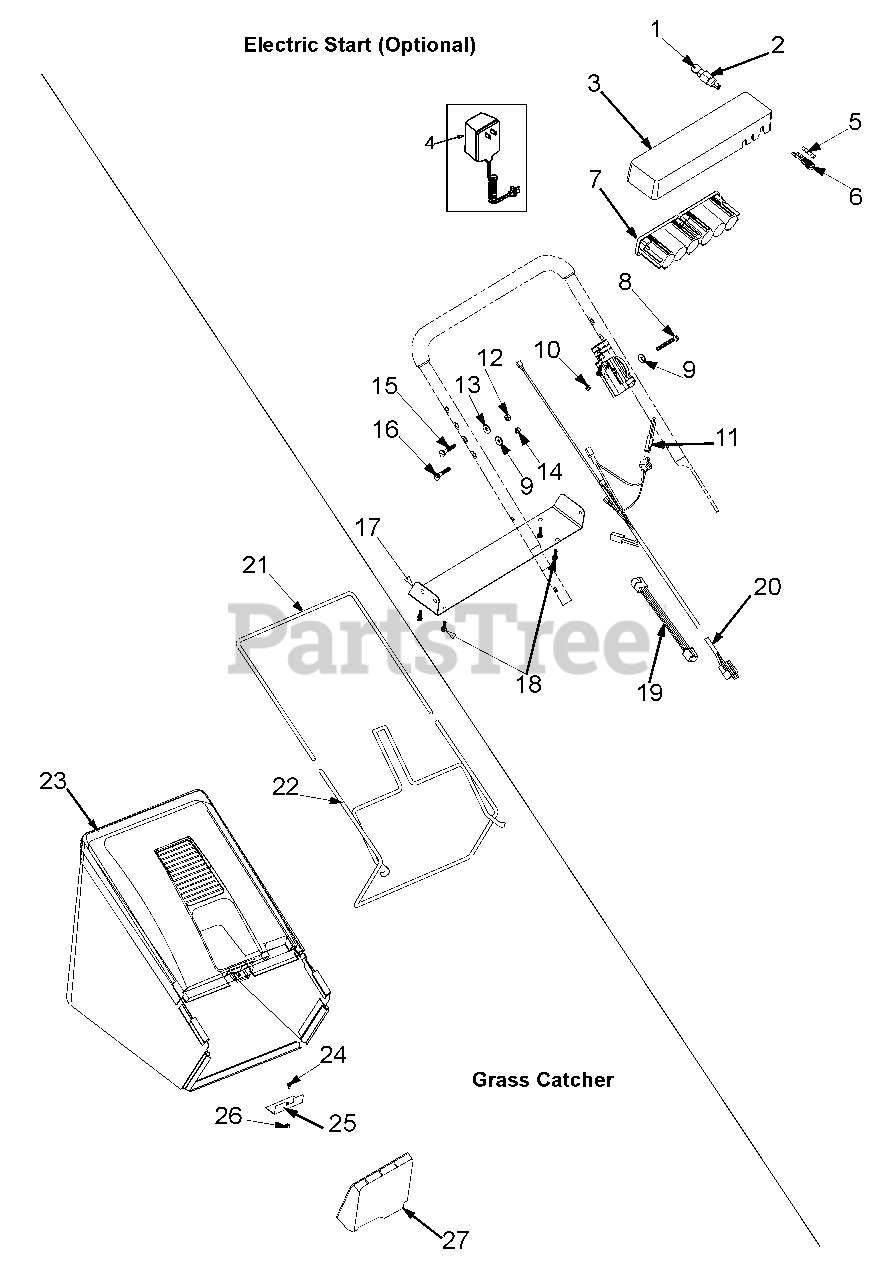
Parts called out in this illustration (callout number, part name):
1	Ignition Key
2	Key Switch
3	Battery Tray
4	Battery Charger
5	Fuse 7.5 Amp
6	Fuse Holder
7	Battery 12V
8	Hex Screw: 1/4-20: 2.0
9	Bell Washer .265 x .75 x .062
10	Special Hex Nut 5/16-18
11	Plug
12	Nut 5/16-18
13	Bell Wash .340 ID x .872 OD
14	Hex Nut 1/4-20
15	Carriage Bolt 5/16-18 x 1
16	Carriage Screw
19	Harness Extension
20	Harness
24	Hex Screw 1/4-14 .625
